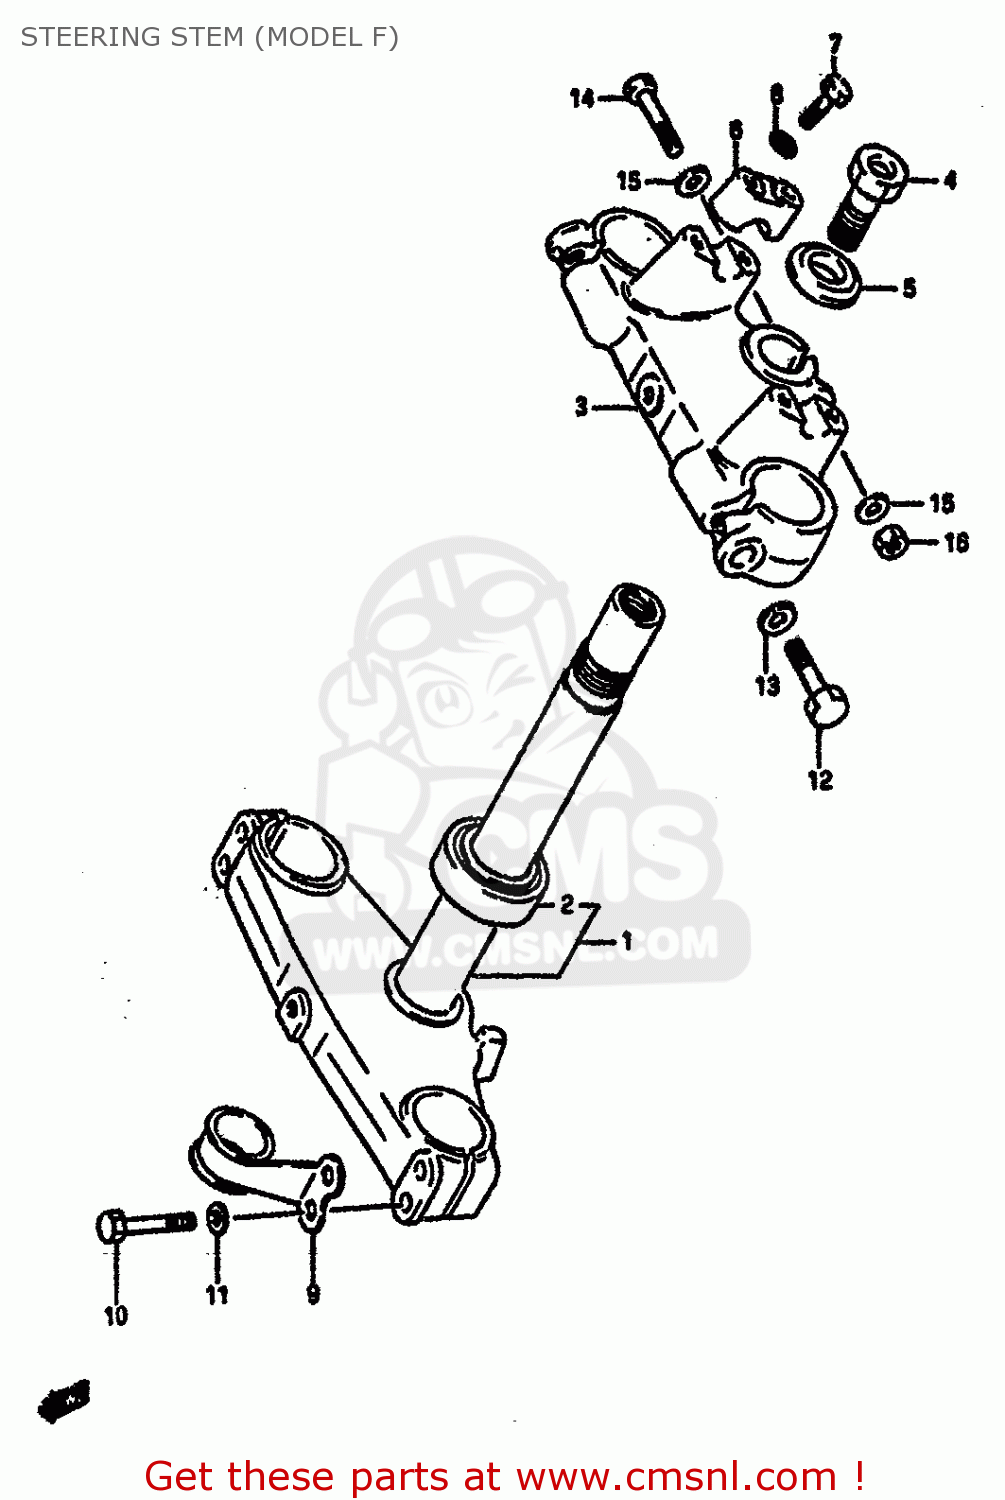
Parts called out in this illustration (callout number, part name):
1	STEM,STEERING
2	BEARING
3	HEAD,STEERING STEM
4	BOLT
5	WASHER
6	HOLDER,HANDLEBAR
7	BOLT
8	WASHER,LOCK,8.
9	GUIDE,CABLE
10	BOLT 8X40
11	WASHER,LOCK,8.
12	BOLT
13	LOCK WASHER
14	BOLT 8X50
15	WASHER
16	NUT
